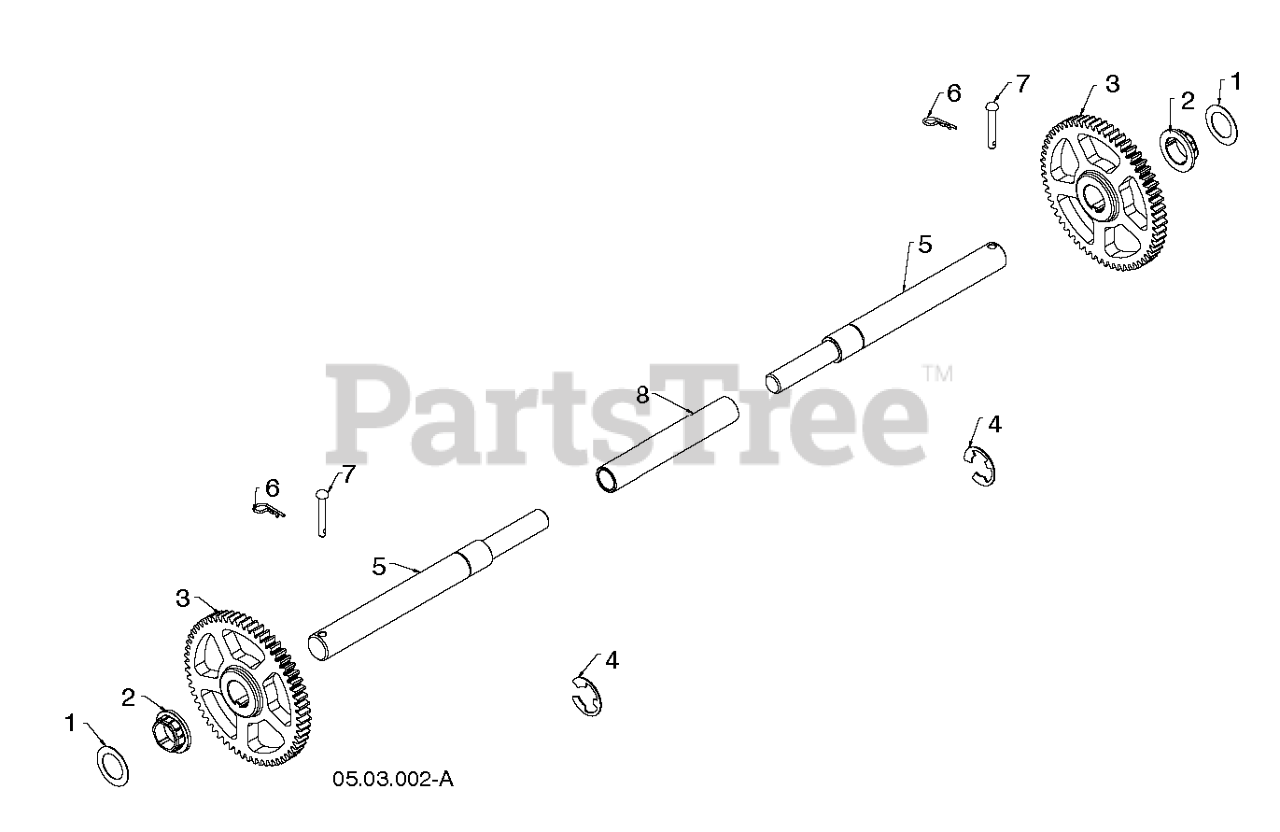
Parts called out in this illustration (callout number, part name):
1	WASHER 1.00
2	BUSHING,HEX BUSHING (1
3	GEAR 59T DRIVEN PWR STR
4	E RING HYT
5	AXLE AXLE, SPLIT SHAFT
6	RETAINER M
7	RIVET
8	SLEEVE SLEEVE, AXLE SLEEVE
